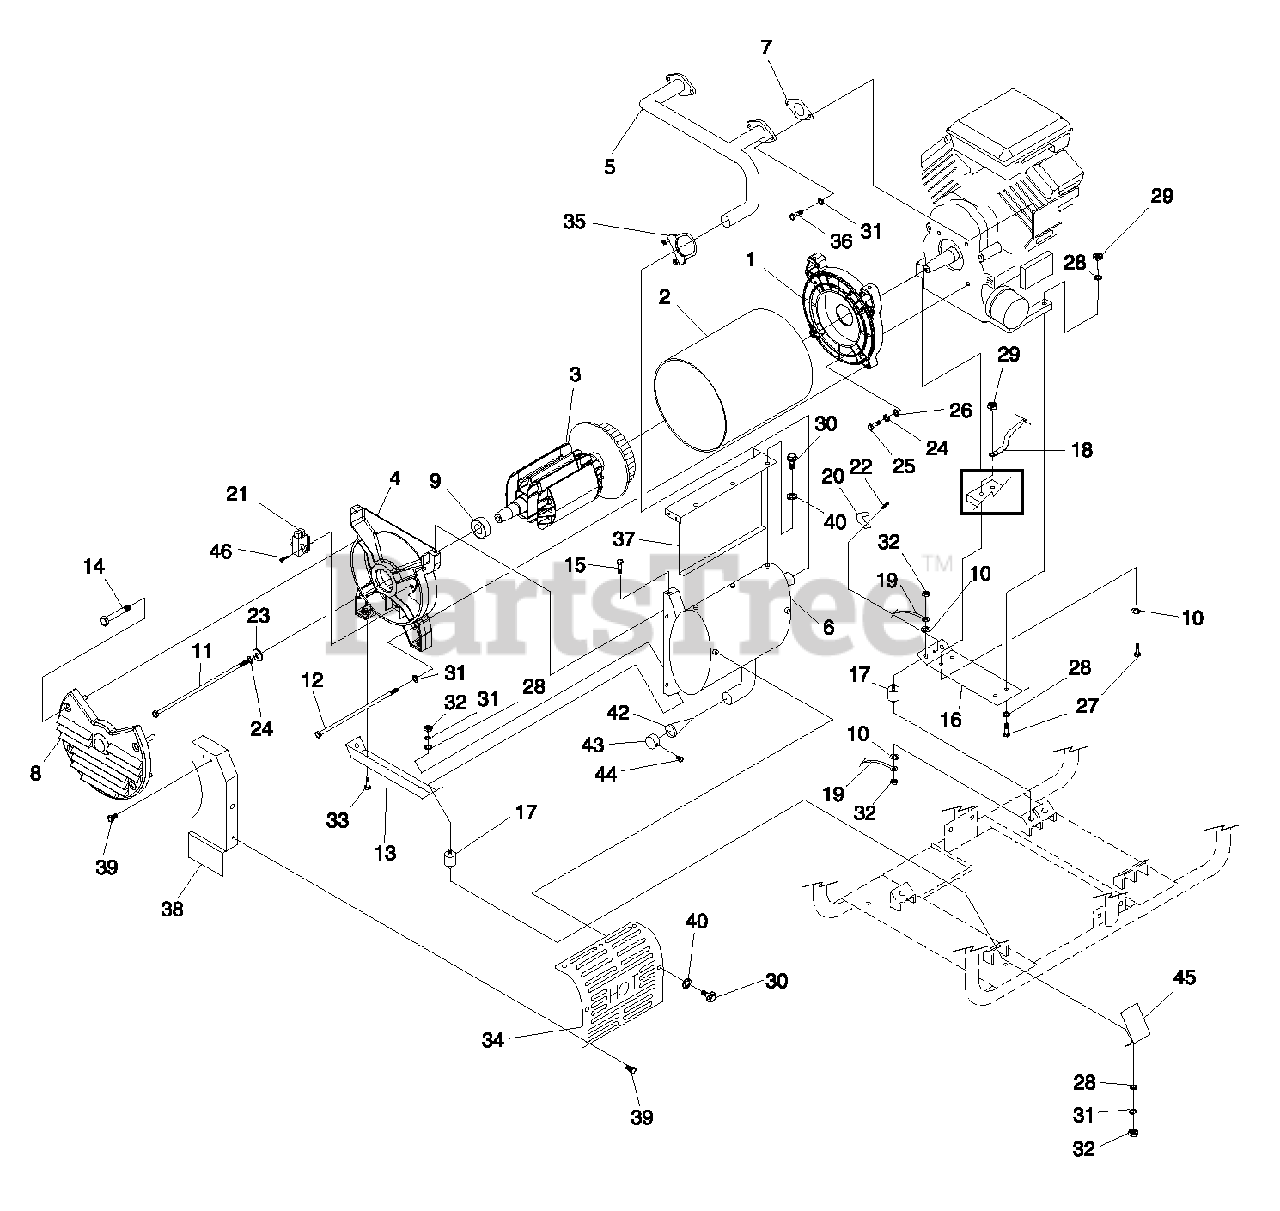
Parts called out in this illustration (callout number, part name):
1	ADAPTOR, ENGINE
2	STATOR 12.5KW
3	ASSEMBLY, ROTOR WITH FAN 12.5KW
4	CARRIER, REAR BEARING
5	EXHAUST MANIFOLD
6	MUFFLER
7	GASKET, EXHAUST
8	COVER, ALTERNATOR AIR IN
9	BEARING
10	5/16 SPECIAL LOCK WASHER
11	SCREW IHHC 3/8-24 X 15.50 G5
12	SCREW IHHC M8-1.25 X 400 G8.8
13	BRACKET, ALT MOUNTING
14	SCREW HHTT #10-32 X 1.75
15	SCREW HHTT M8-1.2 X 20
16	ENGINE MOUNTING PLATE
17	RUBBER MOUNT
18	BATTERY CABLE, BLACK
19	EARTH STRAP 3/8X 3/8
20	CLIP-J VINYL COAT .625 ID
21	ASSEMBLY, BRUSH HOLDER
22	SCREW TAP-R #10-32 X 9/16
23	WASHER FLAT 3/8 ZINC
24	WASHER LOCK 3/8
25	SCREW HHC 3/8-16 X 1-1/4 G5
26	WASHER FLAT 3/8-M10 ZINC
27	SCREW HHC M8-1.25 X 50 G8.8
28	WASHER FLAT 5/16 ZINC
29	NUT LOCK HEX M8-1.25 NYLON INSERT
30	SCREW HHC M6-1.0 X 16 WITH LOCK WASHER
31	WASHER LOCK M8-5/16
32	NUT HEX 5/16-18 STEEL
33	SCREW TAPTITE 3/8-16 X 3/4 BP
34	SHIELD, MUFFLER HEAT
35	U-BOLT & SADDLE
36	SCREW SHC M8-1.25 X 18
37	PANEL, MUFFLER BOX BACK
38	PANEL, MUFFLER BOX END
39	SCREW HHTT M6-1.0 X 12
40	WASHER FLAT 1/4
42	SPARK ARRESTOR SCREEN
43	RETAINER, SPARK ARREST SCREEN
44	SCREW HHTT M4-0.7 X 8
45	SHIELD, RUBBER MOUNT
46	SCREW HHTT M5-0.8 X 16
